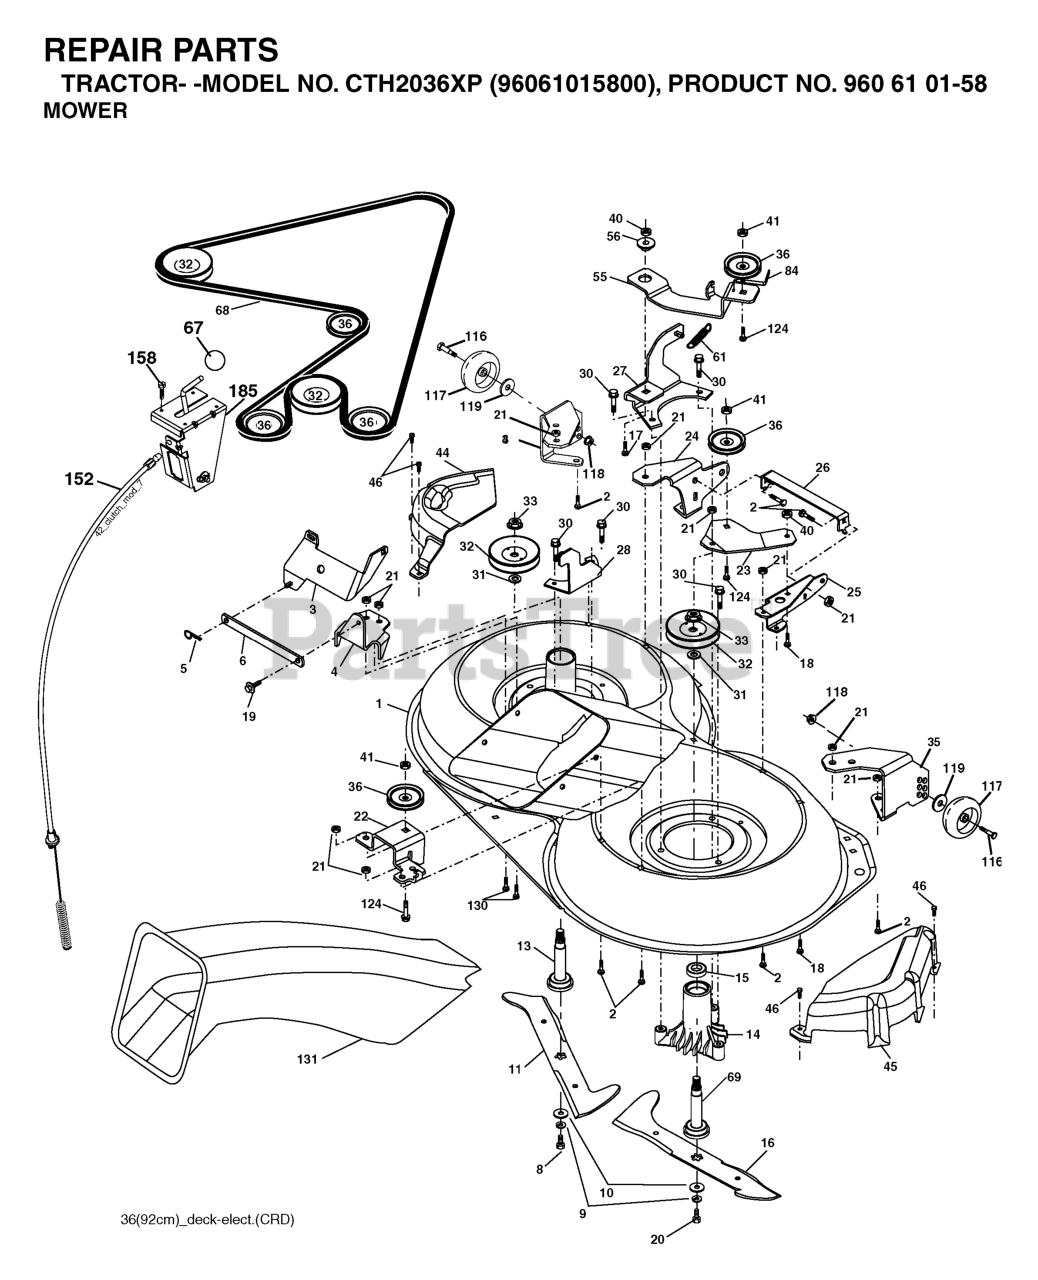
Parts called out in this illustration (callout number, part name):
2	RP BOLT 5/16-18 X3/4 ZN/YEL GR
5	RETAINER-SPRNG RB
6	BAR.SWAY.92.CRD
8	BOLT.3/8-24X1.25 GR8
9	LOCKWASHER
10	WASHER.BLADE
13	SHAFT ASM VENT
14	HOUSING.MANDREL.VENTED (MACHD)
17	BOLT.3/8-14X1.25
19	BOLT SHD 5/16-18
20	BOLT.3/8-24X1.25GR8. LHTHRD
21	LOCKNUT
26	SUPPORT
30	SCREW, WASHER HEAD
31	WASHER.SPACER.MANDREL
33	NUT.FLANGE.LOCK.TOP
36	PULLEY.IDLER.4.25
41	NUT LOCK FLG 3/8-16 UNC
45	COVER.MANDREL.RH.CRD
46	SCREW.1/4-20X5/8
55	ARM.IDLER.92 CRD.2006
56	SPACER.RETAINER.MOWER
61	SPRING
67	KNOB T (3/8 HOLE)
68	HEX-BELT
69	SHAFT.ASM.W/LWR.BRG.RH.THREAD
84	KEEPER, BELT IDLER
116	SHOULDER BOLT
117	RP WHEEL. GUAGE RALLY
118	LOCKNUT
119	WASHER.5/16.FLAT.STE.STD.
124	BOLT.3/8-16X1.50
130	BOLT.CARR.SQNK.5/16-18UNC.X3/4
131	CHUTE BAGGER
158	SCREW
185	HEAD ASM. CABLE CLUTCH
